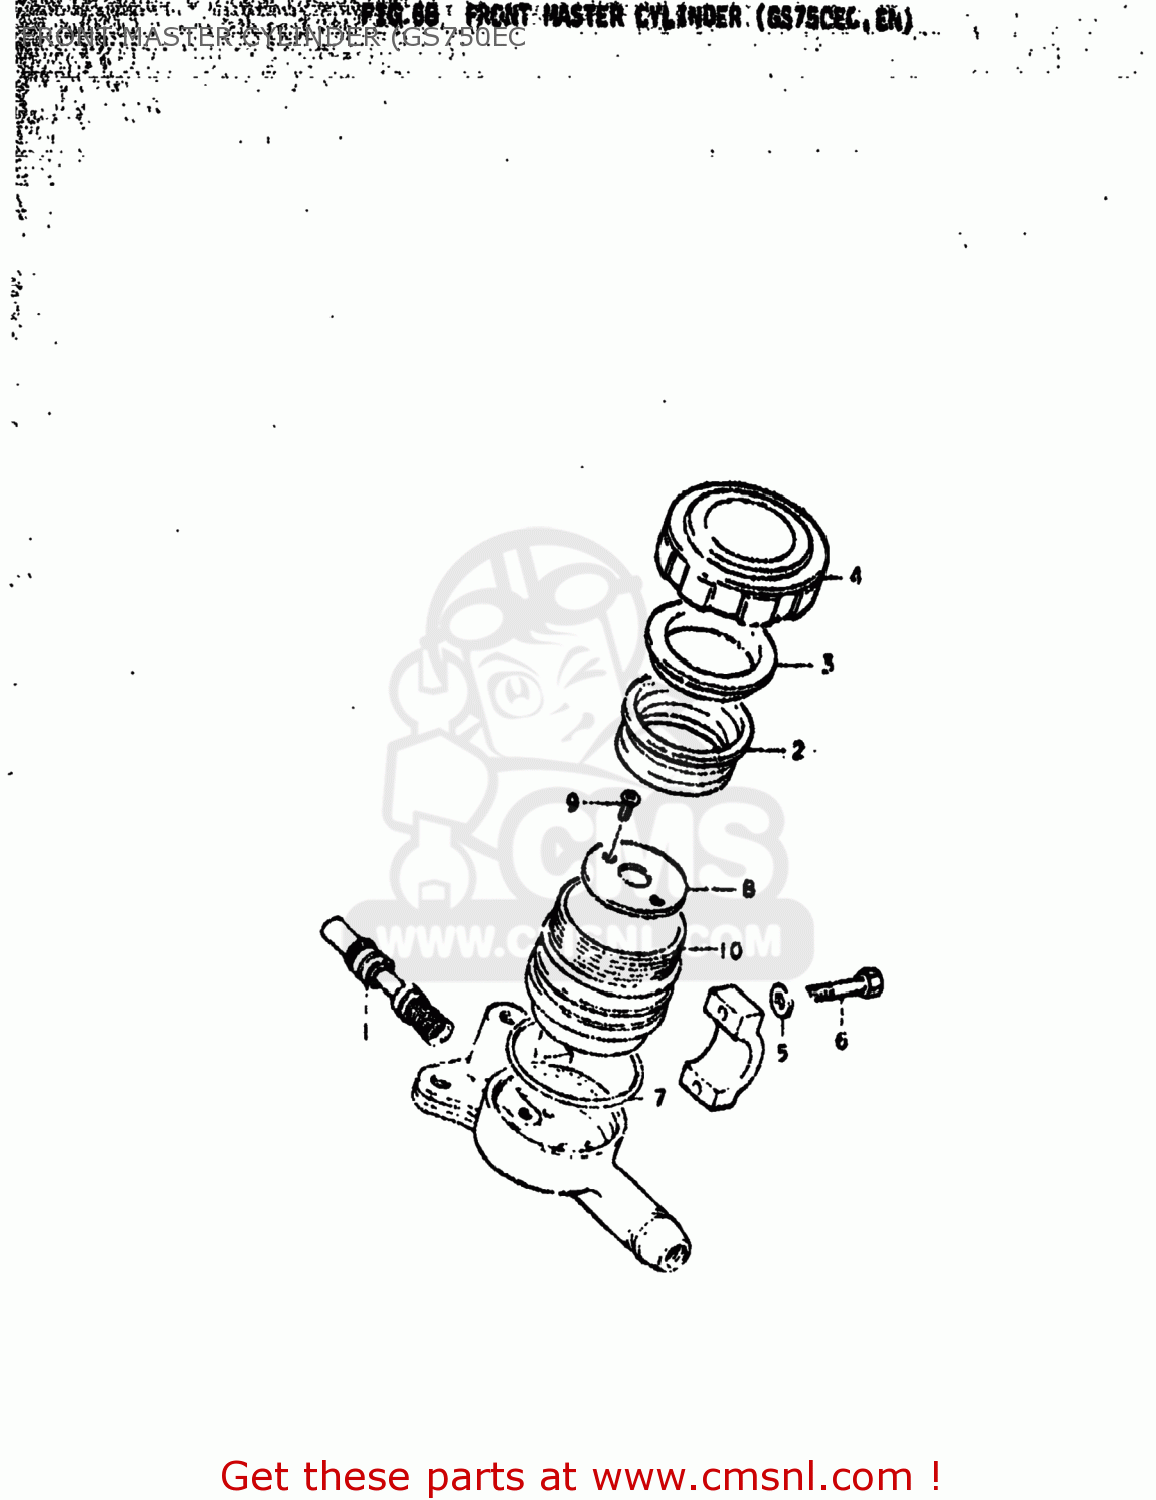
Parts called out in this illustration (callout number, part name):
1	CYLINDER ASSEMBLY,MASTER
2	DIAPHRAGM
3	PLATE,DIAPHRAGM
4	CAP
5	WASHER
6	BOLT
7	O RING
8	PLATE
9	SCREW,MASTER CYLINDER
10	RESERVOIR
